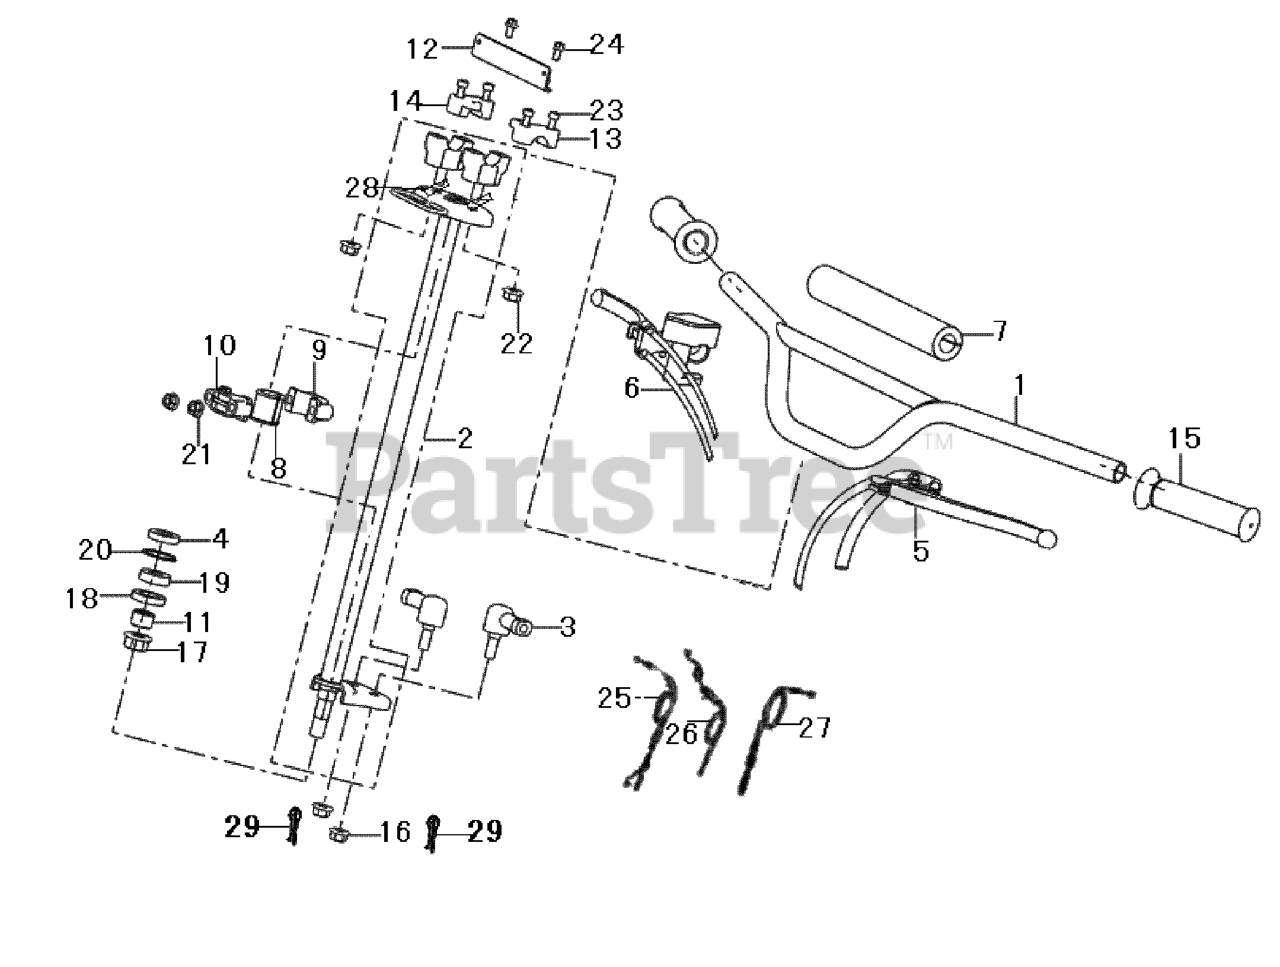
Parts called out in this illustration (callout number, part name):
1	HANDLEBAR
2	SHAFT, STEERING
3	BALL JOINT
4	SEAL, OIL
5	LEVER ASSY., LEFT
6	LEVER ASSY, RIGHT
7	PAD, HANDLEBAR
8	BUSHING, STEERING
9	COLLAR HALF, REAR BUSHING
10	COLLAR HALF, FRONT BUSHING
11	COLLAR, STEERING SHAFT
12	BRACKET
13	HANDLEBAR HOLDER, LEFT
14	HANDLEBAR HOLDER, RIGHT
15	GRIP, HANDLEBAR
18	OIL SEAL
19	BEARING
20	CIRCLIP
25	CABLE ASSY. 100cc, THROTTLE
26	CABLE ASSY., REAR BRAKE
27	CABLE ASSY., FRONT BRAKE
28	HANDLEBAR HOLDER (BOTTOM)
29	PIN, COTTER
